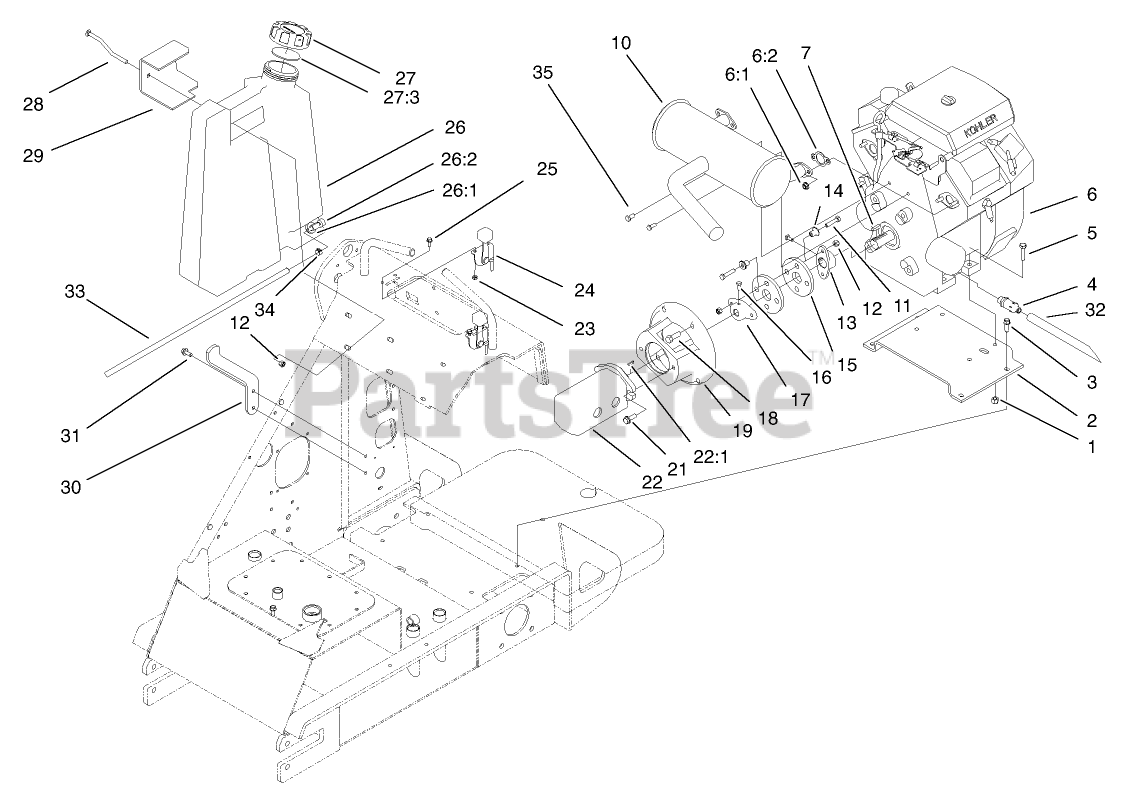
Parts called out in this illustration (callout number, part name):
1	NUT-LOCK, NI
2	MOUNT-ENGINE
3	SCREW-TAPTITE
4	VALVE-DRAIN, OIL
5	SCREW-HH
6:1	NUT-HF
6:2	GASKET-EXHAUST
7	KEY-SQUARE
10	MUFFLER-KOHLER
11	SCREW-HH
12	NUT-LOCK, NI
13	HUB-ENGINE
14	SPACER
15	COUPLING-RUBBER
16	SCREW-SQH
17	HUB-PUMP
18	SCREW-HH
19	MOUNT-PUMP
21	SCREW-HHF
22	PUMP-GEAR, TANDEM
22:1	KEY-SQUARE
23	NUT-LOCK, NI
24	CONTROL-CHOKE / THROTTLE
25	SCREW-HHF
26	RH FUEL TANK ASM
26:1	BUSHING
26:2	VALVE-FUEL
27	CAP-FUEL, GAS
27:3	GASKET-VENTED
28	BOLT-MOUNT
29	PLATE-MOUNT
30	MOUNT-BOTTOM, TANK
31	SCREW-HWHTF
33	HOSE-FUEL
34	CLAMP-HOSE
35	SCREW-HH
